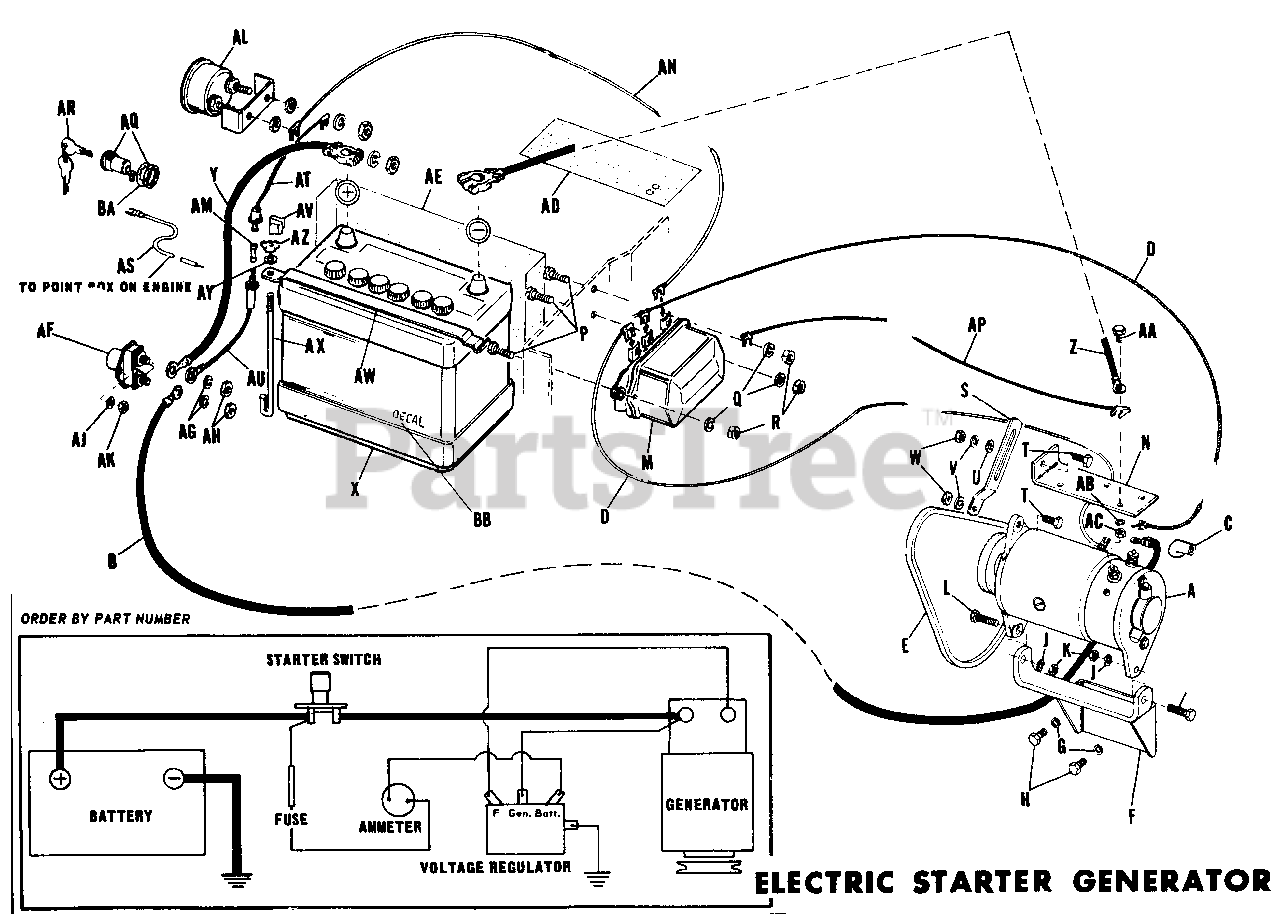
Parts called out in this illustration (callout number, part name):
A	Motor - Generator
B	Generator Start Cable
C	Terminal Cover
D	Reg. Gen. Wire
E	V-BELT, 39.12"
F	Support Assembly
G	Lock Washer, 5/16"
H	Hex. Capscrew, 5/16"-18 x 3/4" lg.
J	Lock Washer, 5/16"
K	Full Hex. Nut, 5/16"-18
L	Hex. Capscrew, 5/16"-18 x 1-1/4"
M	Voltage Regulator
P	Hex. Capscrew, 1/4"-20 x 3/4" lg.
Q	Lock Washer, 1/4"
R	Full Hex. Nut, 1/4"-20
S	Belt Tightener
T	Hex. Capscrew, 5/16"-18 x 3/4" lg.
U	Plain Washer, 5/16"
V	Lock Washer, 5/16"
W	Full Hex. Nut, 5/16"-18
Y	Cable (Battery to Starter)
Z	Cable (Battery to Ground)
AA	Hex. Capscrew, 1/4"-20 x 5/8" lg.
AB	Lock Washer, 1/4"
AC	Full Hex. Nut, 1/4"-20
AD	Battery Insulation
AE	Fuel Tank Insulation
AF	Starter Switch
AG	Lock Washer, 3/8"
AH	Full Hex. Nut
AJ	Lock Washer, 1/4"
AK	Full Hex. Nut, 1/4"-20
AL	Ammeter
AM	Fuse, 20 AMP.
AN	Wire (Ammeter to Regulator)
AP	Wire (Ground to Ground)
AQ	Ignition Switch
AS	Wire (Switch to Engine)
AT	Wire (Fuse to Ammeter)
AU	Wire (Fuse to Starter)
AV	Clip Fuse
AW	Battery Bracket
AY	Lock Washer, 1/4"
AZ	Wing Nut, 1/4"-20
BA	Lock Washer, Int. 13/16"
BB	Film (SIMPLICITY)
